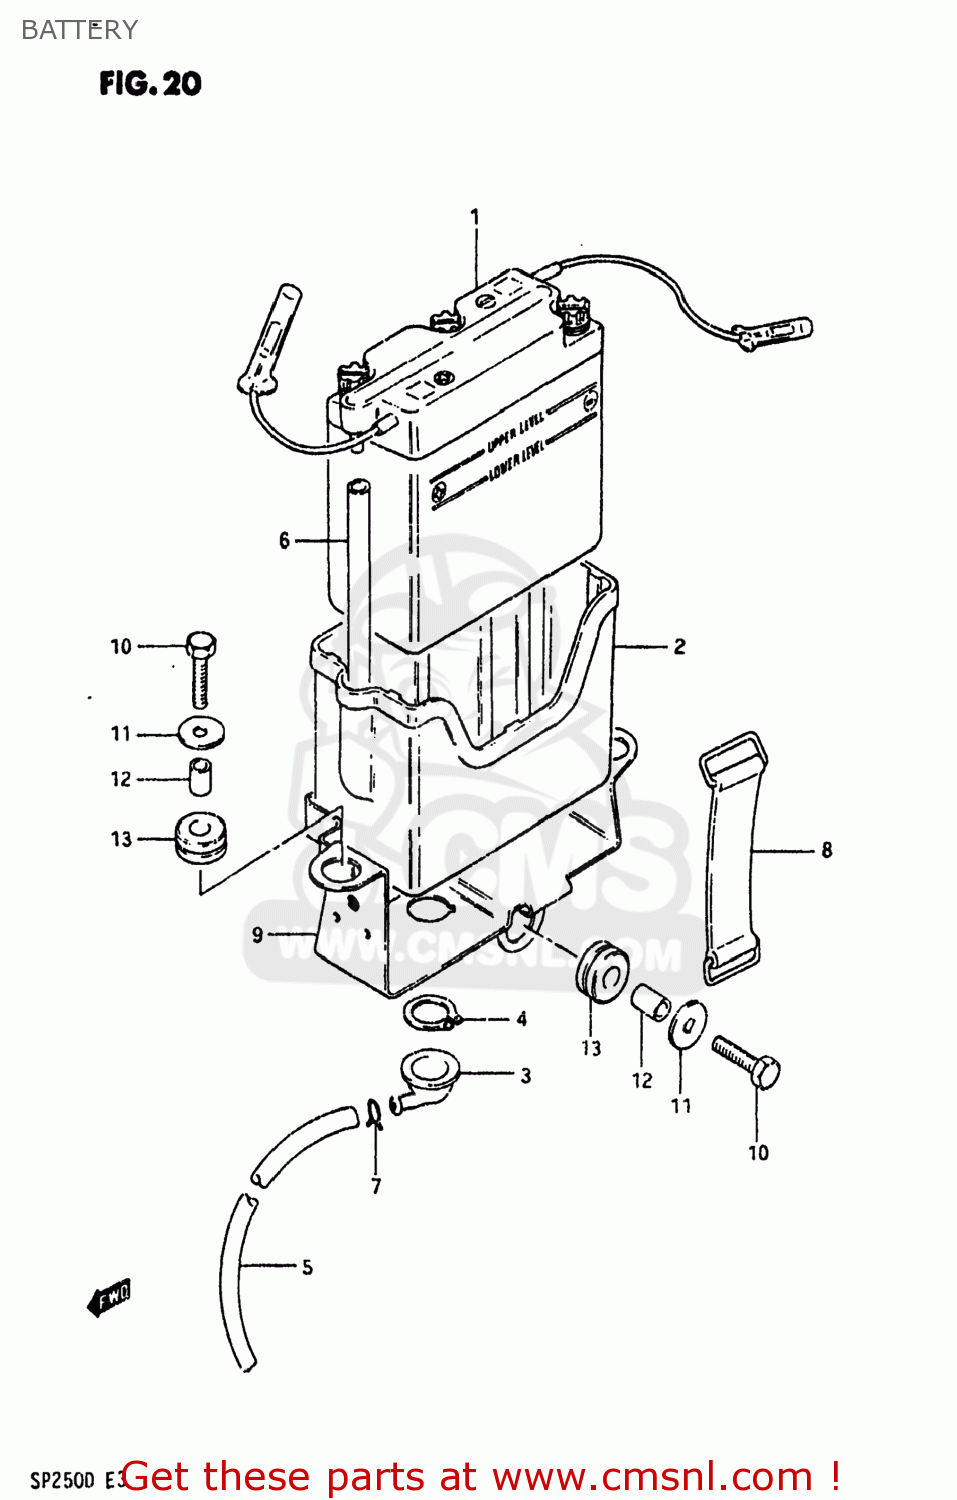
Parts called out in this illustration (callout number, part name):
1	BATTERY ASSEMBLY
2	CASE,BATTERY
3	FUNNEL,BATTERY EXHAUST
4	CIRCLIP
5	HOSE,BATTERY EXHAUST
6	HOSE, EXHAUST (L:45)
7	CLIP
8	BAND
9	HOLDER,BATTERY
10	BOLT, UPPER
11	WASHER (6.5X20X1.2)
12	SPACER(6.1X9X7.5)
13	CUSHION
